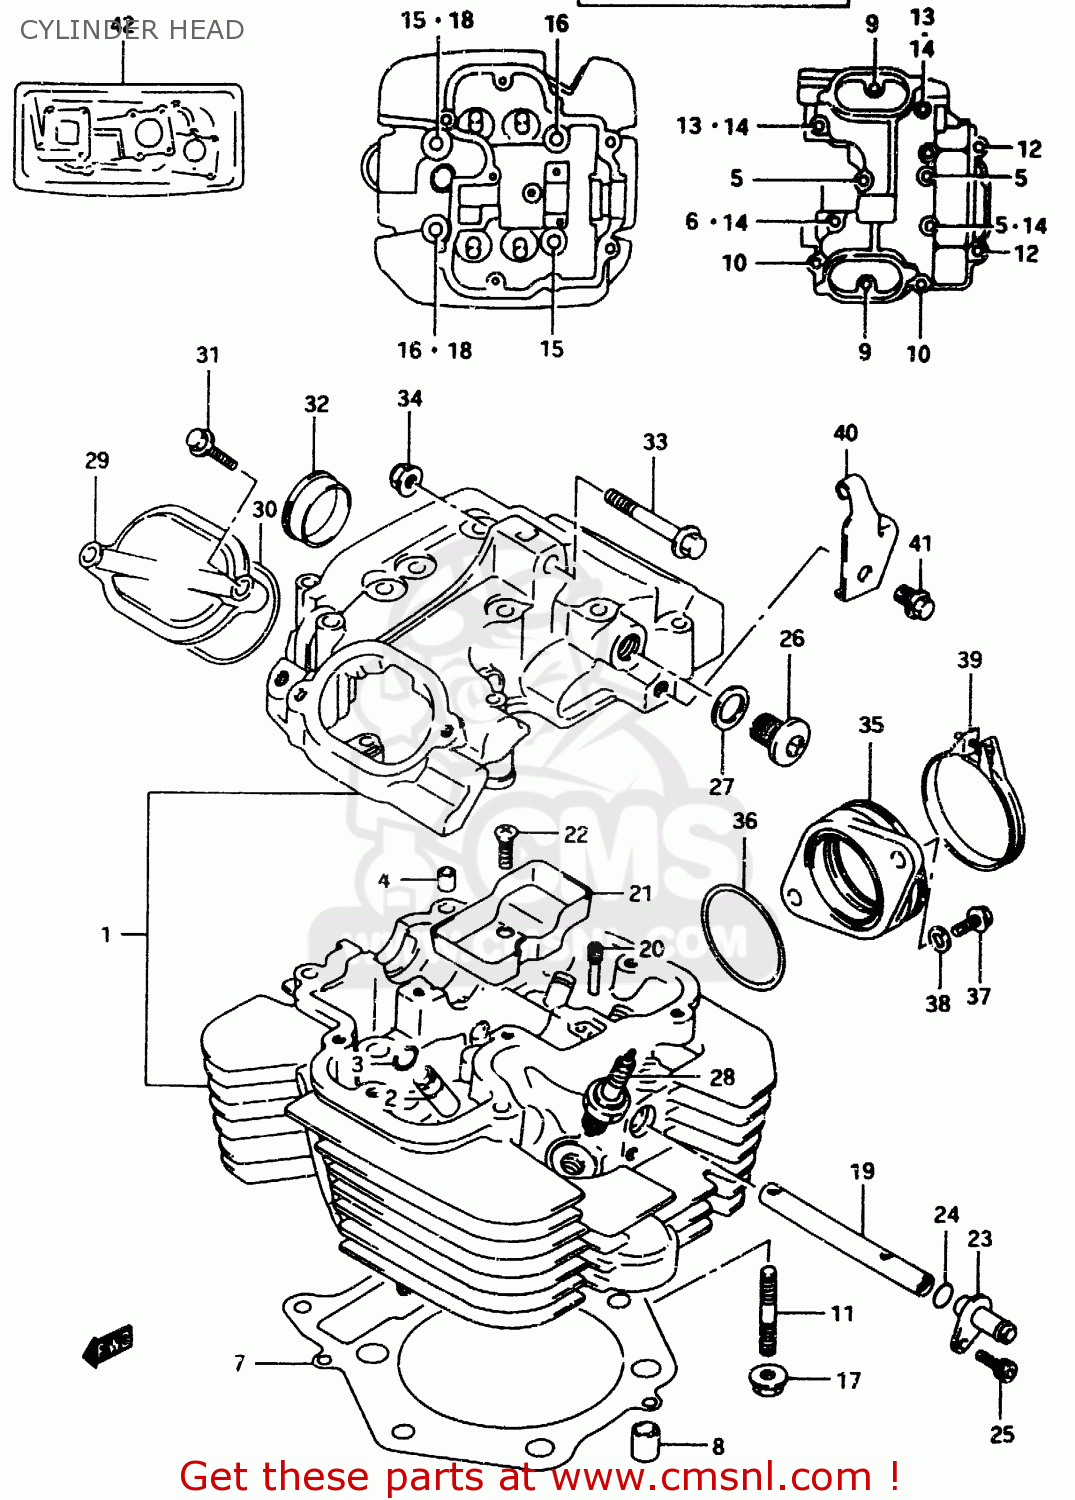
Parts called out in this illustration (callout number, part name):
1	HEAD ASSY, CYLINDER
2	GUIDE,VALVE
3	RING,SNAP
4	PIN(6.2X8X11)
5	BOLT
6	BOLT 6X55
7	GASKET,CYLINDER HEAD (NAS)
8	PIN
9	BOLT
10	BOLT
11	BOLT,STUD
12	BOLT(6X130)
13	BOLT
14	GASKET (NAS)
15	BOLT(10X190)
16	BOLT(10X215)
17	NUT
18	GASKET(10.5X22X2) (NAS)
19	PIPE,CYLINDER HEAD OIL
20	SCREW (L:19.5)
21	PLATE,CYLINDER HEAD CHAMBER
22	SCREW
23	UNION,CYLINDER HEAD OIL
24	O RING,HEAD GASKET
25	BOLT,OIL FILLE
26	PLUG
27	GASKET(13.8X18.8X4.8) (NAS)
28	PLUG,SPARK(DPR9EA-9)
29	CAP,INSPECTION
30	O RING(D:2.4,ID:23)
31	BOLT
32	PLUG(OD:30)
33	BOLT(8X50)
34	NUT
35	PIPE,INTAKE
36	O RING(D:2.4,ID:45.7)
37	BOLT
38	LOCK WASHER
39	CLAMP
40	HOLDER,DECOMP CABLE
41	BOLT 8X16
42	GASKET SET (NAS)
